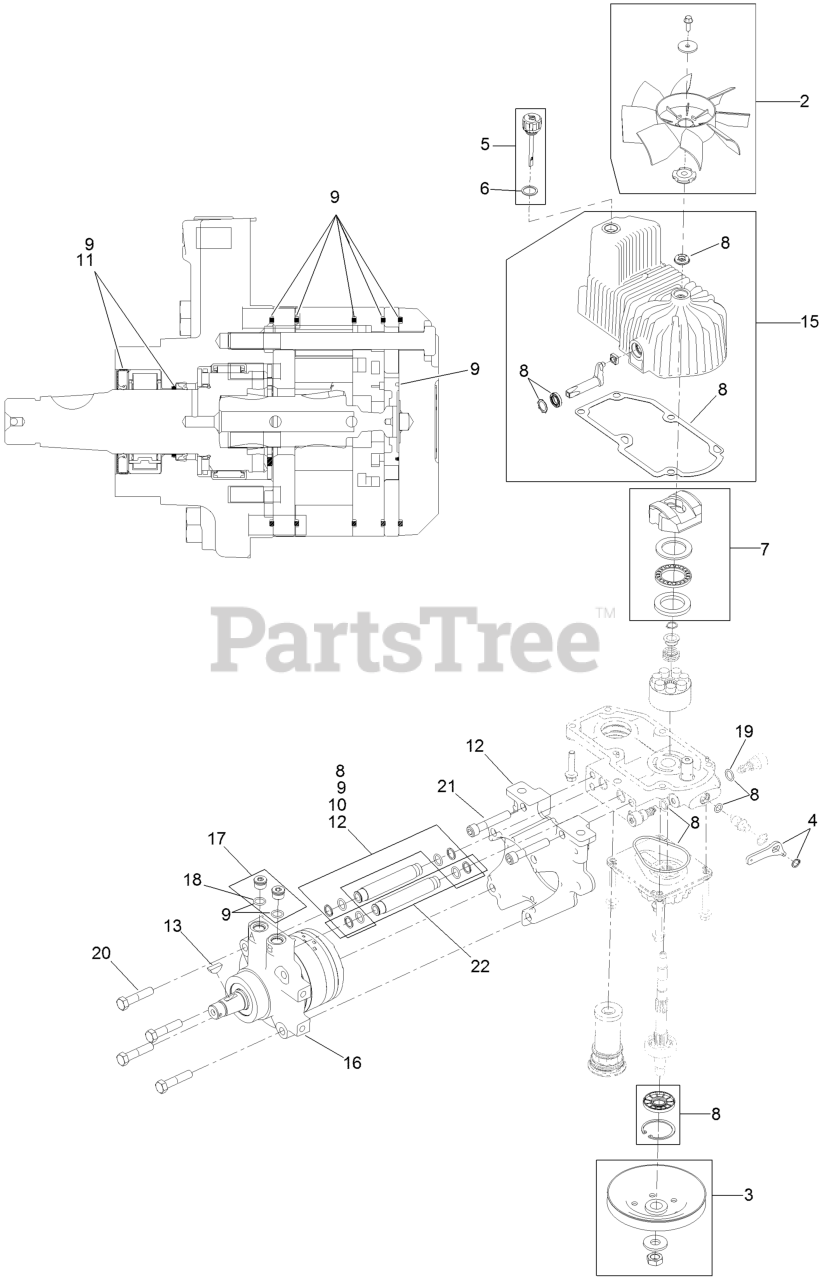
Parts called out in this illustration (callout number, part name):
2	FAN KIT
3	PULLEY KIT
4	HANDLE-BYPASS VALVE, HYDRO
5	DIPSTICK-HYDRO W/GASKET
6	GASKET-DIPSTICK, HYDRO
7	SWASH BLOCK KIT
8	PUMP SEAL KIT
9	MOTOR SEAL KIT
10	TUBE SEAL KIT
11	OUTPUT SHAFT SEAL KIT
12	NOSE CUP-UHT
13	KEY-WOODRUFF
15	HOUSING-HYDRO, LH
16	MOTOR-HYDRAULIC LH 240CC
17	MAGNETIC PLUGS SERVICE KIT
19	O-RING-CHECK VALVE
20	SCREW HH
21	SCREW-HSH
22	HYDRAULIC TUBE KIT
